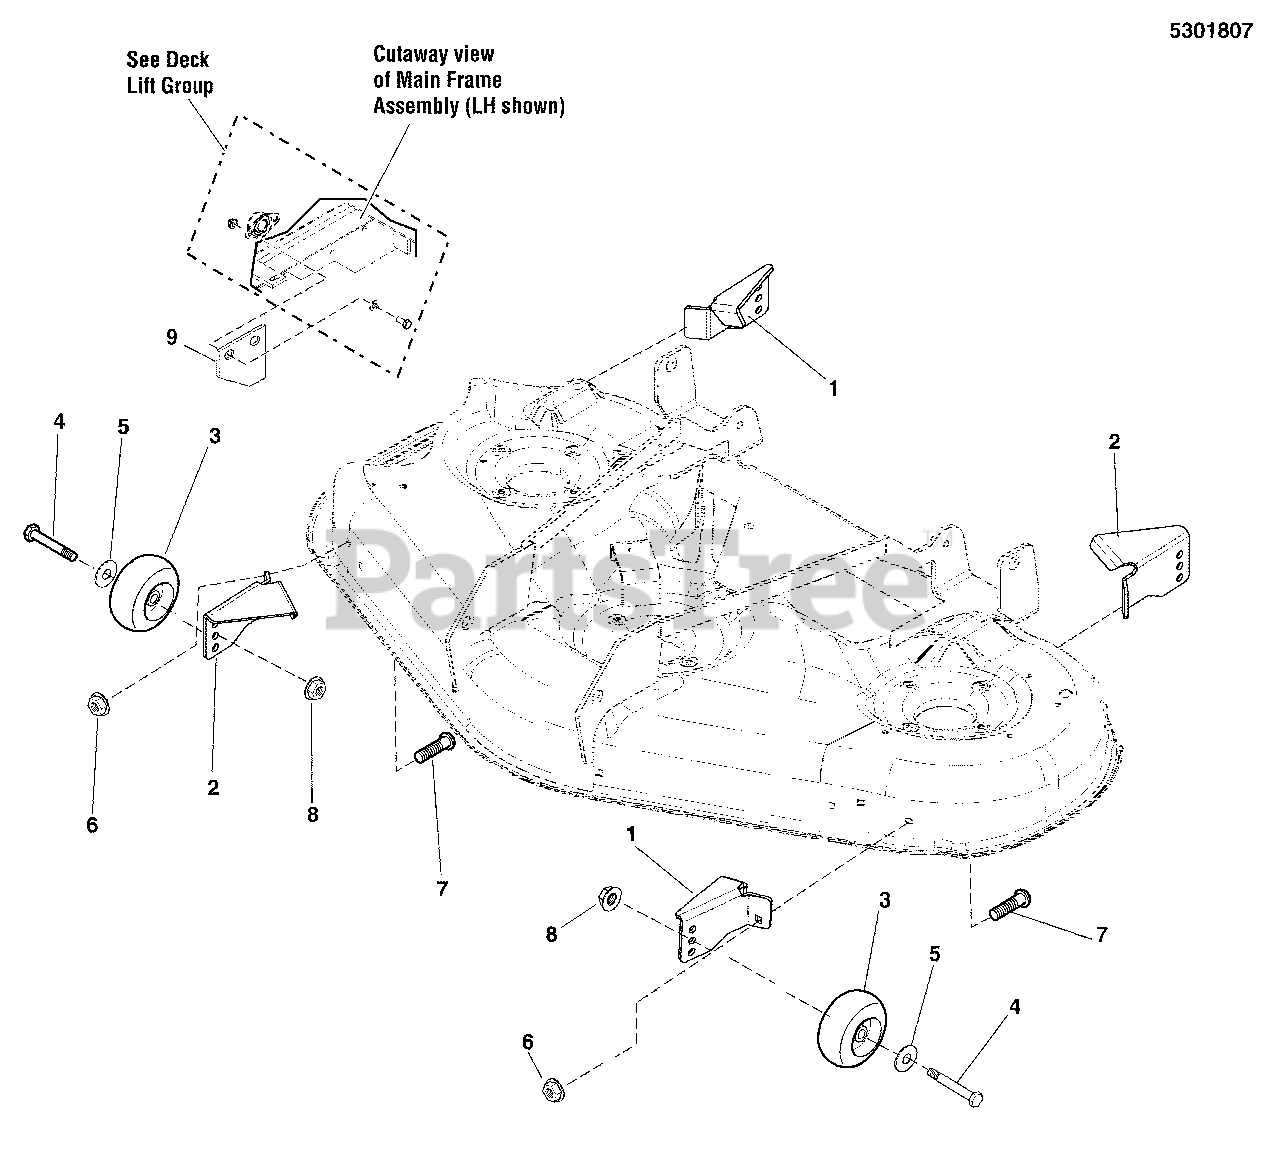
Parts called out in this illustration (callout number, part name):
1	BRKT, GAUGE WHEEL
2	BRKT, GAUGE WHEEL
3	WHEEL, GAUGE BLACK POLY 5" DIA
4	BOLT, SHLDR 3/8-16X3.41 .750 THRD YELLOW
5	WASHER, 0.500 (0.51IDX1.00ODX.10THK) BLK
6	NUT, HEX FLANGE 5/16-18, WHIZ LK SM, YZ
7	BOLT, RD HD SH SQ NK 5/16-18X0.875 G5 BLK
8	NUT, HEX FLANGE 3/8-16 ESNA BLK
9	PLATE, DECK STOP, 355Z - RED
